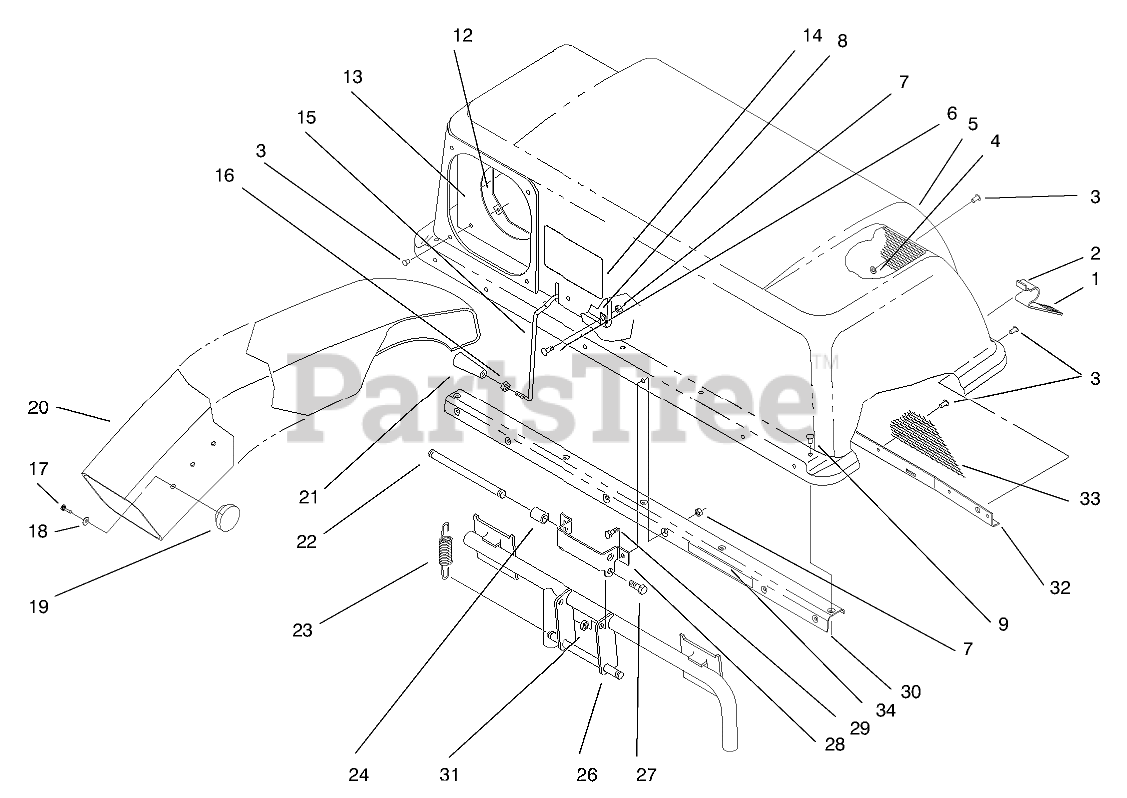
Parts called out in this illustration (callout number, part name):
2	Latch-Bag
3	RIVET-BLIND
4	WASHER-FLAT
5	TOP-BAGGER
6	SCREW-PPH
7	NUT-LOCK, NI
8	CLAMP
12	CLAMP-SEAL
13	SEAL-CHUTE
14	DECAL
15	FEELER-FILL, BAG
16	NUT-JAM
17	SCREW-PPHTF
18	WASHER-PLAIN
20	CHUTE-DISCHARGE
21	HANDLE-TAPERED
22	PIN-SPRING
23	SPRING-EXTENSION
24	Spacer
26	FRAME ASM
27	SCREW-HH
28	HINGE-BAG TOPB
29	SCREW-HH
30	Stiffener Assembly (Incl. Ref. #34)
31	NUT-LOCK, NI
32	Screen Support
33	SCREEN-BAGGER
34	DECAL-CAUTION
